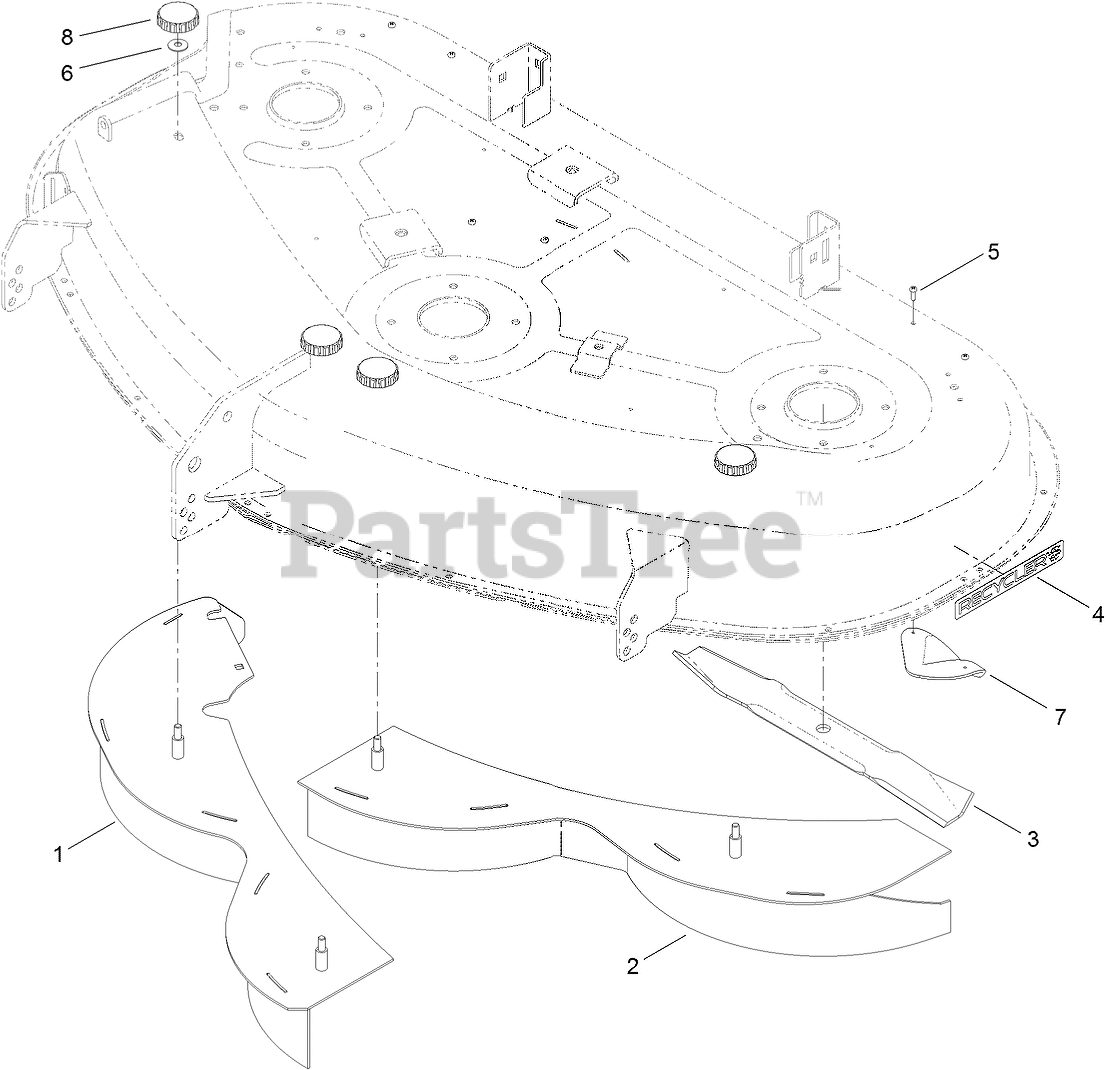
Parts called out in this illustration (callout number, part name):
1	RH BAFFLE ASM
2	LH BAFFLE ASM
3	BLADE-MULCH, 17.50 INCH
4	DECAL-RECYCLER
5	SCREW-PPH
6	WASHER-BELLEVILLE
7	PLATE-KICKER
